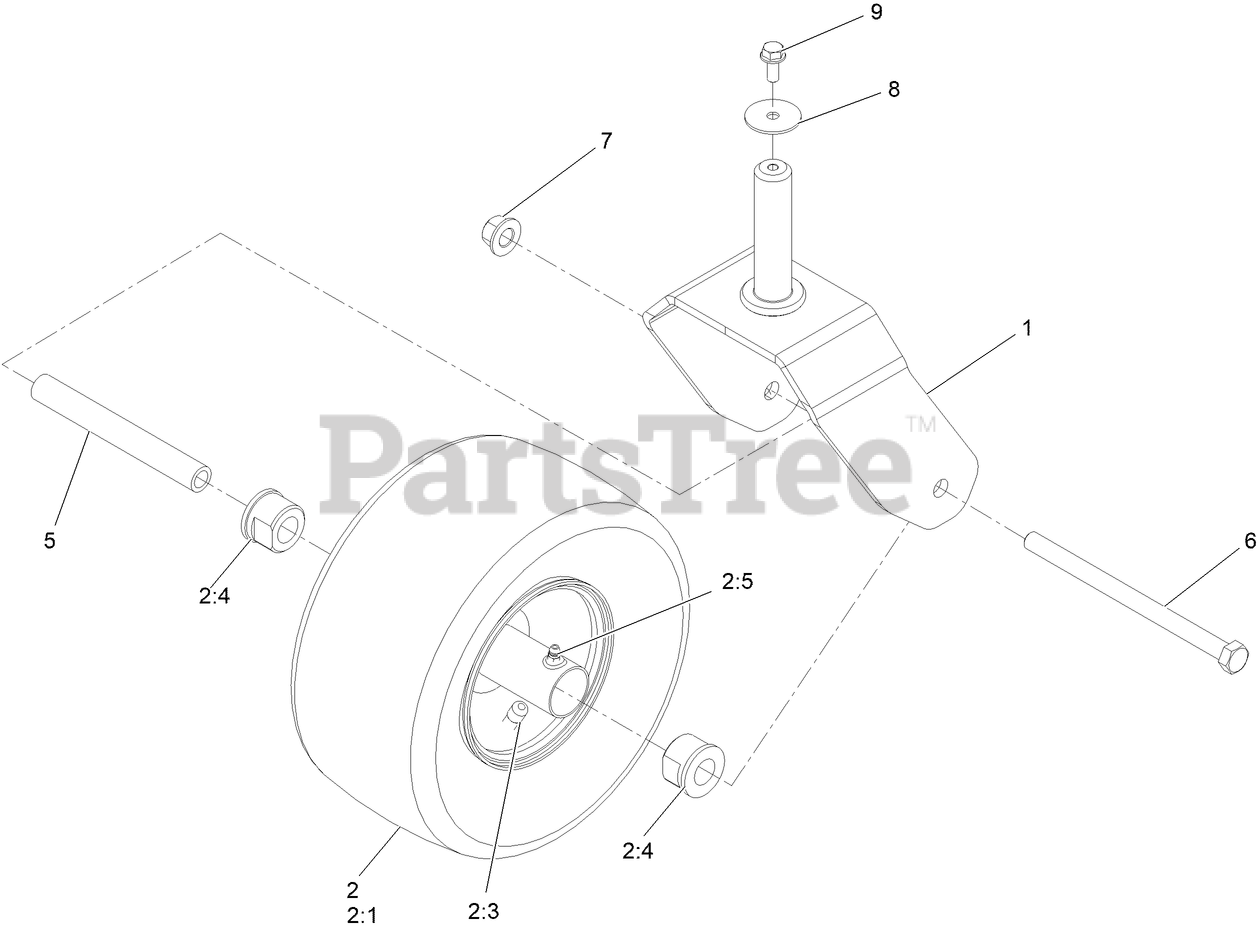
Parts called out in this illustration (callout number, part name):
2	TIRE ASM
2:3	Stem-Valve
2:4	BUSHING-FLANGE
2:5	Zerk 1/4-28 Str Thrd Forming
5	SPACER-SPANNER
6	SCREW-HH
7	Nut-Lock 1/2-13
8	WASHER-FLAT
9	SCREW-HHF
